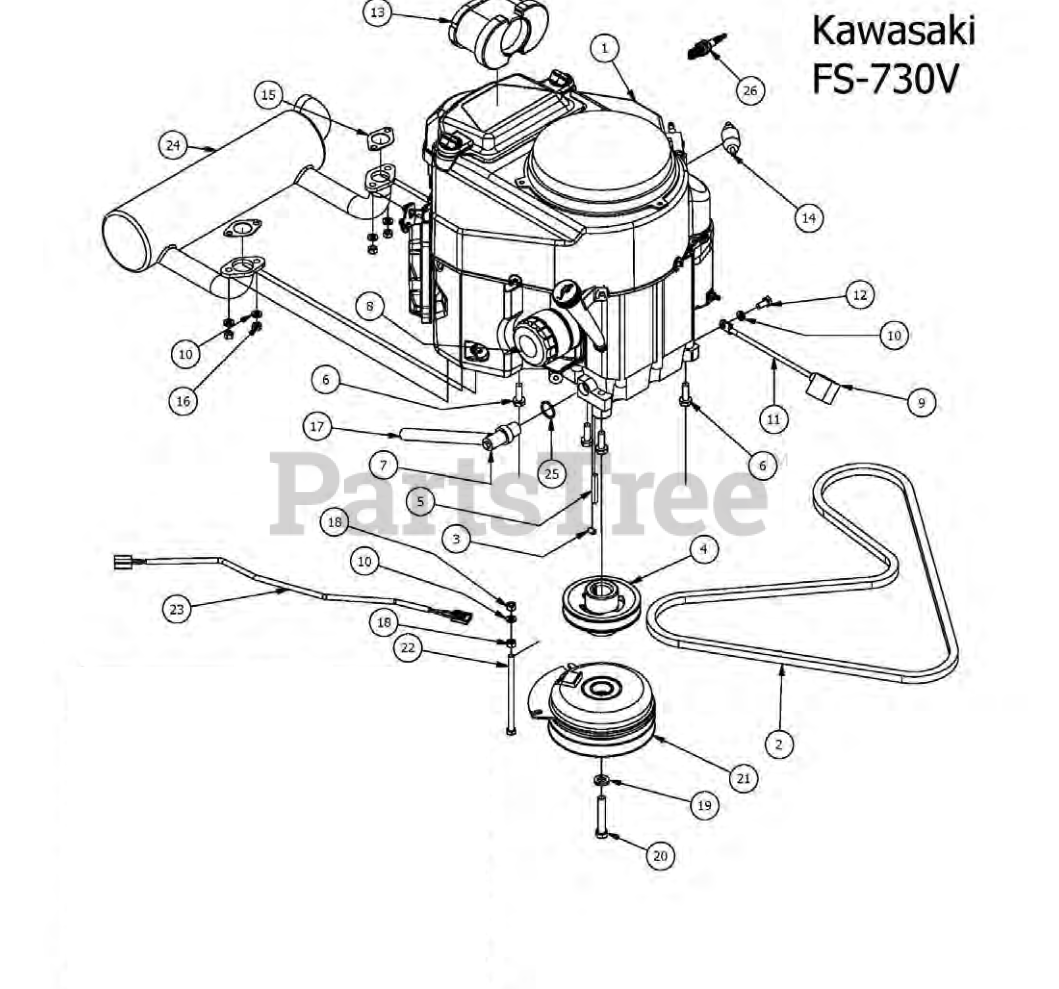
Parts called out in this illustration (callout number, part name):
1	FS730V Engine
2	75.8 Pump Belt
3	5/16 Set Screw
4	4 3/4 Motor Pulley
5	1/4 x 2 Square key Stock
6	3/8 x 1 1/8 bolt
8	Kawasaki Oil Filter
9	Black Boot For Ground Cable
10	5/16" Lock Washer
11	Ground Cable
12	M8x1.20x20MM Hex head bolt
13	Kawasaki Air Filter
14	Universal Inline Fuel Filter
15	Exhaust Gasket
16	MB-1.25 Zinc Nut
17	1/2 Clear Braded Hose Priced/Foot
19	7/16" Lock Washer
20	7/16" x 2 1/2" Hex Bolt
21	Clutch Assembly
22	5/16-18 x 5-1/2 GR 5 Hex Bolt
23	Clutch Pigtail
24	Exhaust Kawasaki FS/FR
26	Spark Plug- Kawasaki
